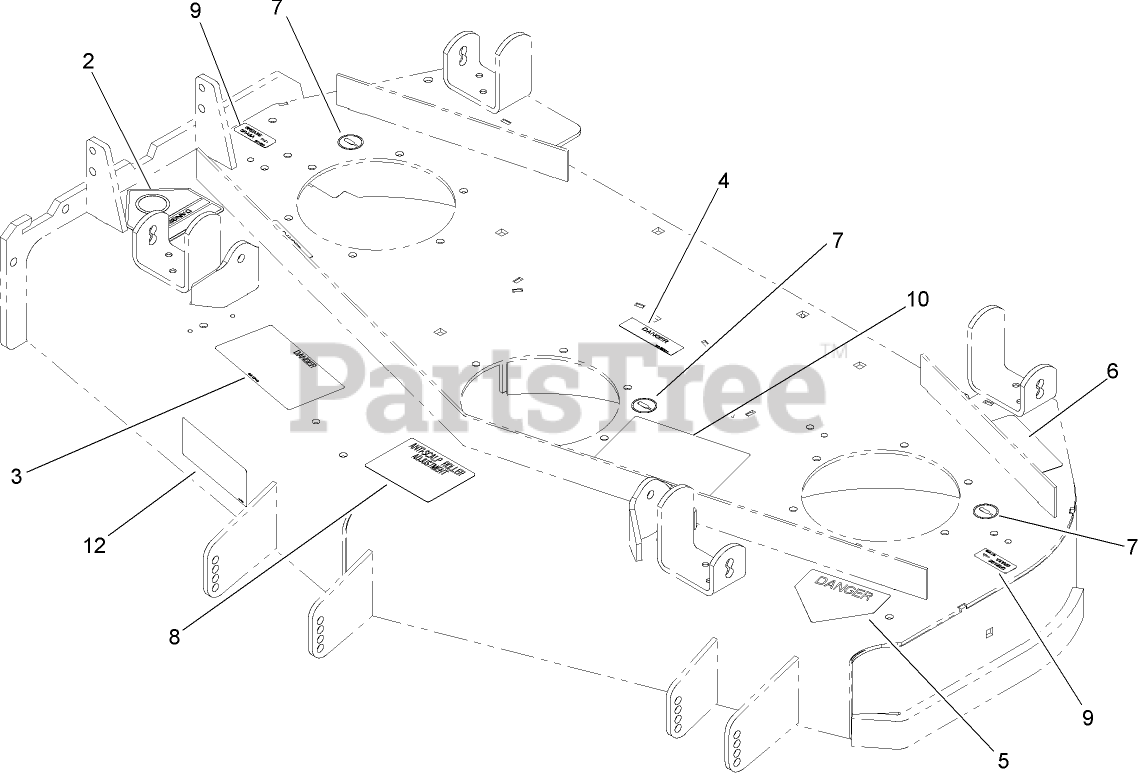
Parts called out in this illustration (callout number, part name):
2	DECAL-DANGER
3	DECAL-DANGER, THROWN OBJECT
4	DECAL-COVER, MISSING
5	DECAL-DANGER
6	DECAL-TORQUE
7	DECAL-GREASE
8	DECAL-SCALP, ANTI
9	Decal-Grease
10	DECAL-AID, SERVICE
